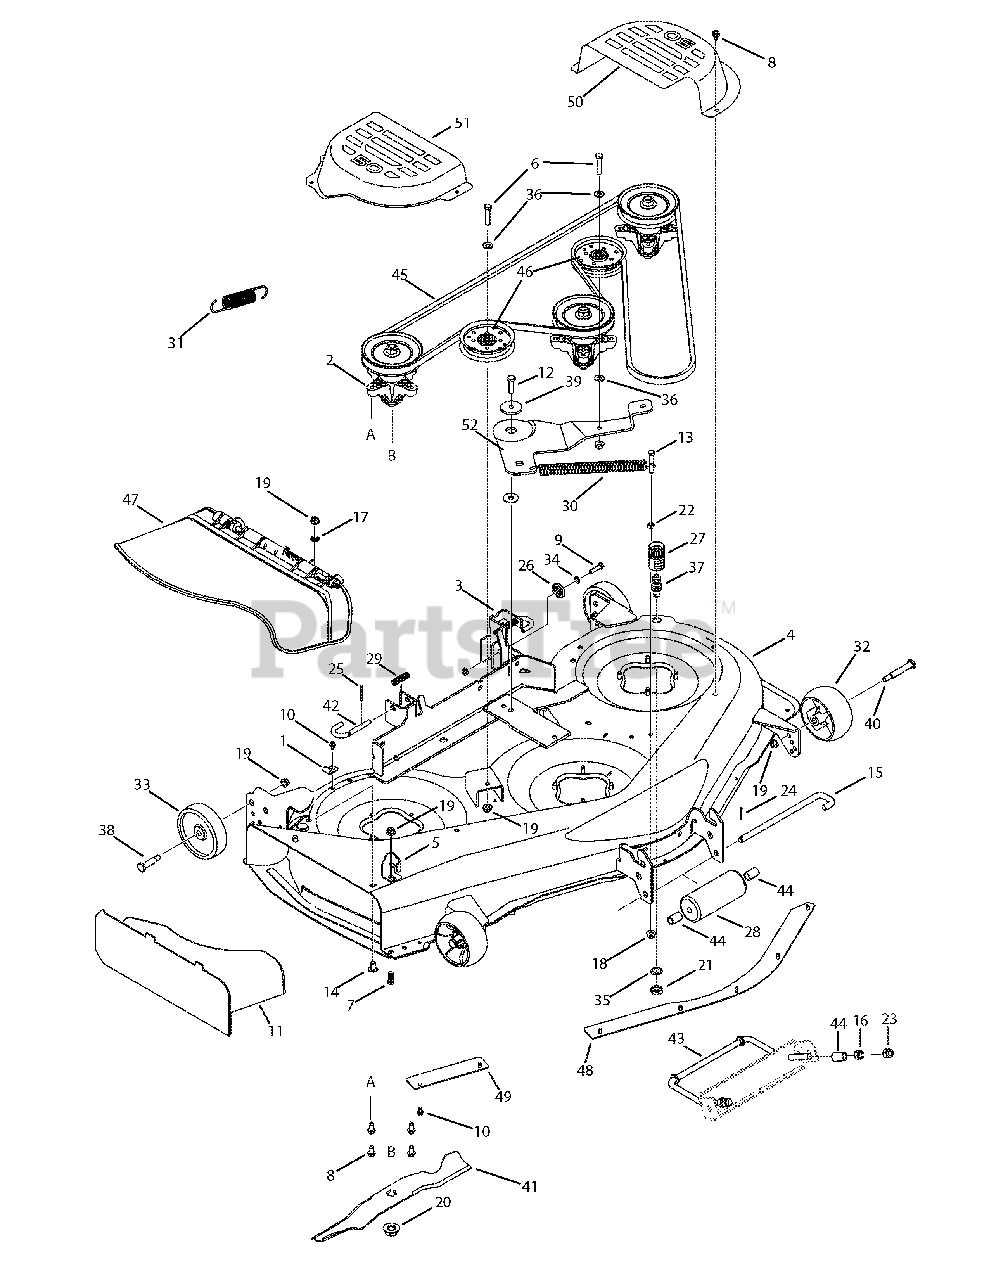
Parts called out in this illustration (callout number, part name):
1	Hook, Retainer
2	Spindle Assembly
3	Hanger Bracket Assembly
4	Weldment, 50-inch Deck
5	Chute Stop
6	Screw, 3/8-16, 1.75
7	Screw, 3/8-16 x 1.0
8	Screw, 5/16-18 x .75
9	Screw, 5/16-18, 1.25, Gr5
10	Screw, 1/4-20 x 0.5
11	Mulch Plug
12	Screw, 3/8-16, 1.25
13	Screw, 5/16-18 x 2.00
14	Screw, Carriage, 3/8-16 x .75
15	Roller Pin
16	Hex Nut, 1/2-13
17	Push Nut Retainer
18	Nut, Nylon Lock, 5/16-18
19	Nut, Nylon Lock, 3/8-16
20	Nut, Hex, Flange, 5/8-18
21	Nut, Hex, M16-1.5
22	Nut, Hex, 5/16-18, Gr5
23	Hex Lock Nut, 1/2-13
24	Pin, Cotter, 3/32 x 1.00
25	Pin, Cotter, 1/8 x 1.25
26	Deck Adjustment Gear
27	Coupler, Hose
28	Roller
29	Spring, Compression, .531 x 1.75
30	Spring, Extension, .94 x 6.74
31	Spring, Lift Assist
32	Deck Wheel, 5.0
33	Deck Wheel, 5.0
34	Washer, Lock, 5/16
35	Lock Washer, 5/8"
36	Washer, Flat, .406 x .875 x .059
37	Port, Water
38	Shoulder Screw
39	Spacer, Shoulder, .884 x .190
40	Shoulder Screw
41	Blade, 17.90
42	Rod, Deck Release .375 Dia.
43	Rod, Deck Adjust
44	Spacer, .550 x .750 x 1.125
45	Belt, V-Type
46	Pulley, Idler, 4.25"
47	Chute Assembly, Side Discharge
48	Deck Skirt, Center
49	Deck Skirt, RH
50	LH Belt Cover
51	RH Belt Cover
52	Idler Bracket
